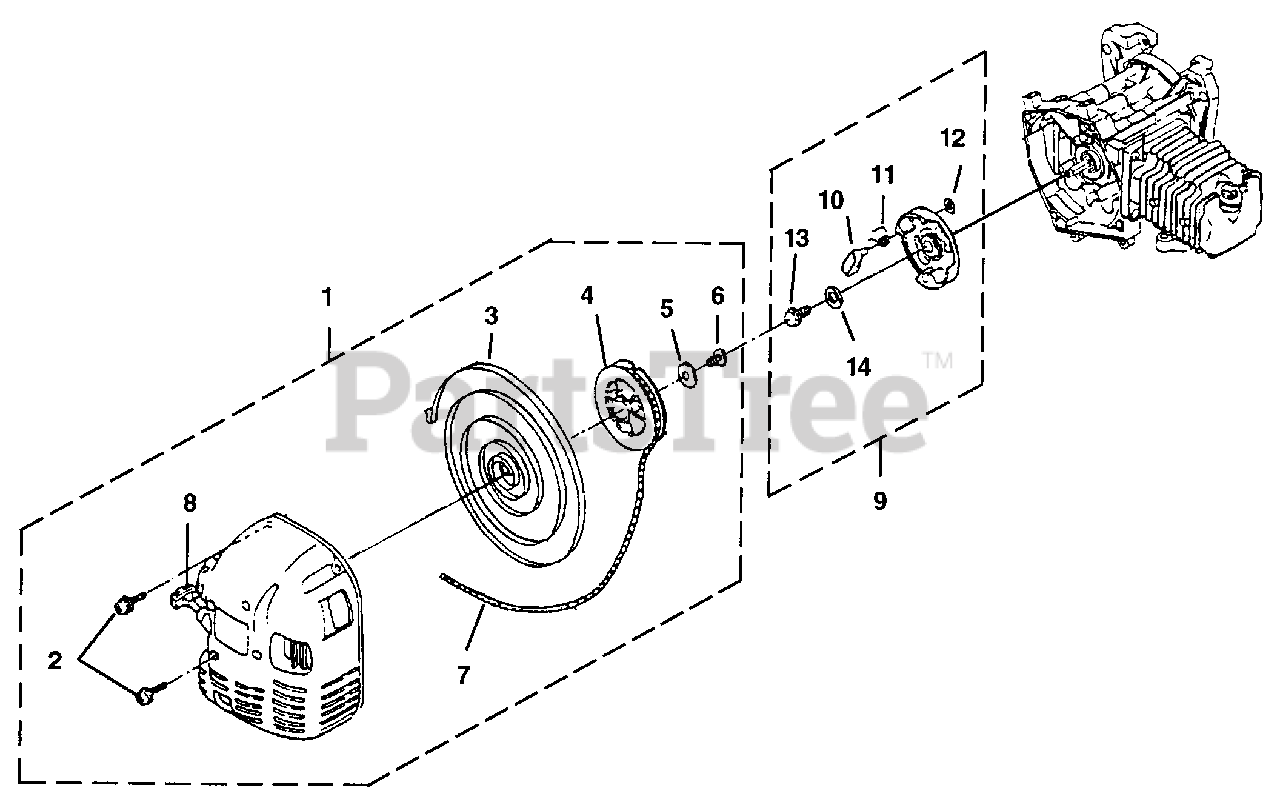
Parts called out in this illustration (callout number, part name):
1	STARTER COMPLETE
2	SCREW-Socket Hd (M5 x 20 W SW)
6	SCREW (M5 x 12)
7	ROPE-Starter
9	STARTER CUP ASSEMBLY
11	SPRING-Return
13	BOLT ASSEMBLY (M6 x 16)
14	WASHERS (M5)
